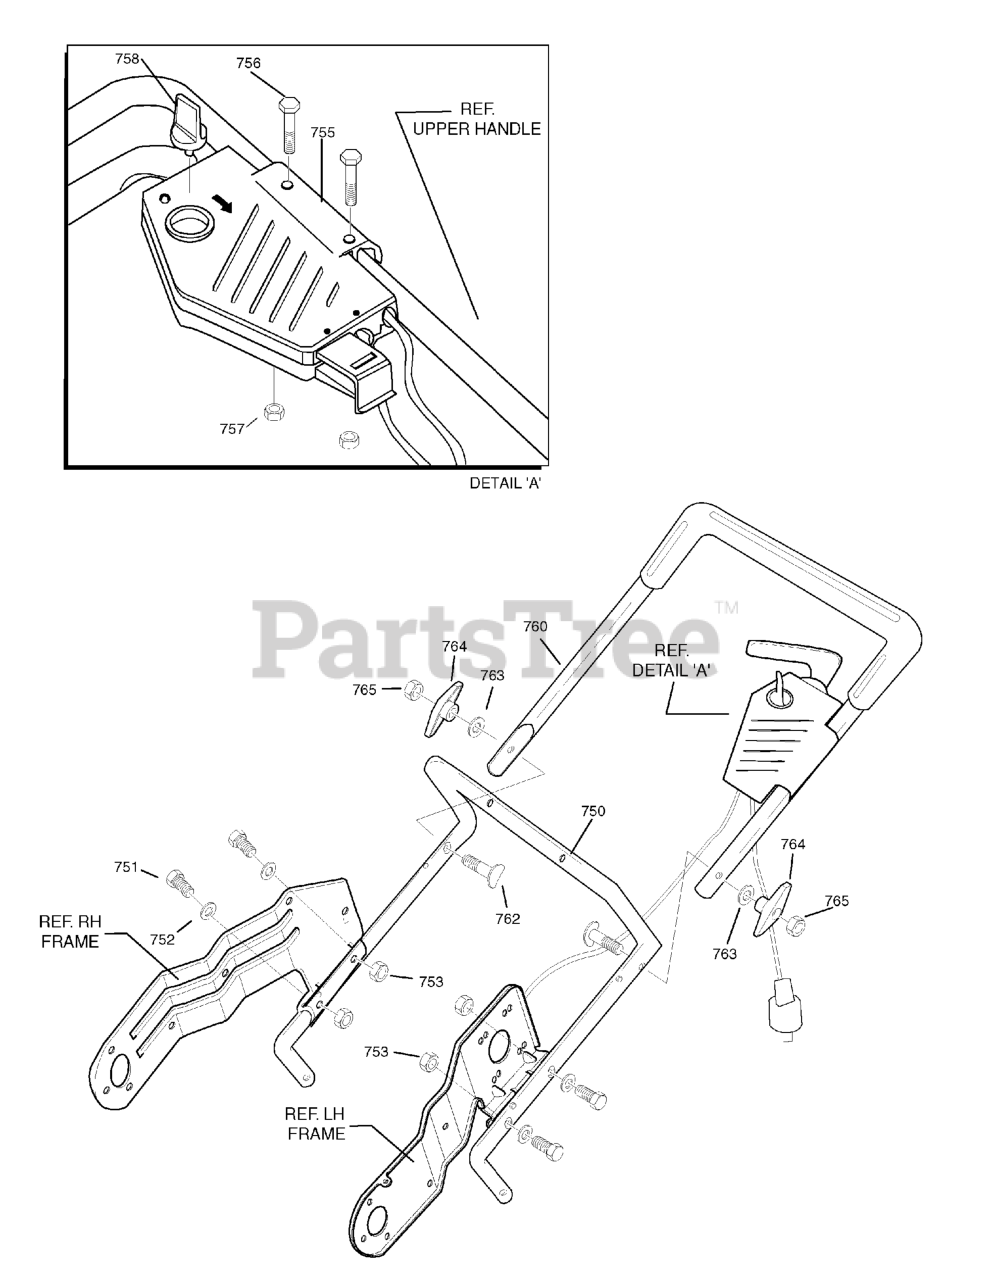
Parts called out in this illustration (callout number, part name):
750	HANDLE, LOWER
751	SCREW, 1/4-20 x 1.25
752	FLATWASHER
753	NUT, 1/4-20
755	ASSEMBLY, SWITCH BOX
756	SCREW, 10-24
757	NUT, #10-24
758	KEY, SWITCH BOX
760	UPPER HANDLE ASSEMBLY
762	BOLT, 5/16-18 x 2.00
763	WASHER, FORMED
764	T KNOB
765	NUT, 5/16-18
